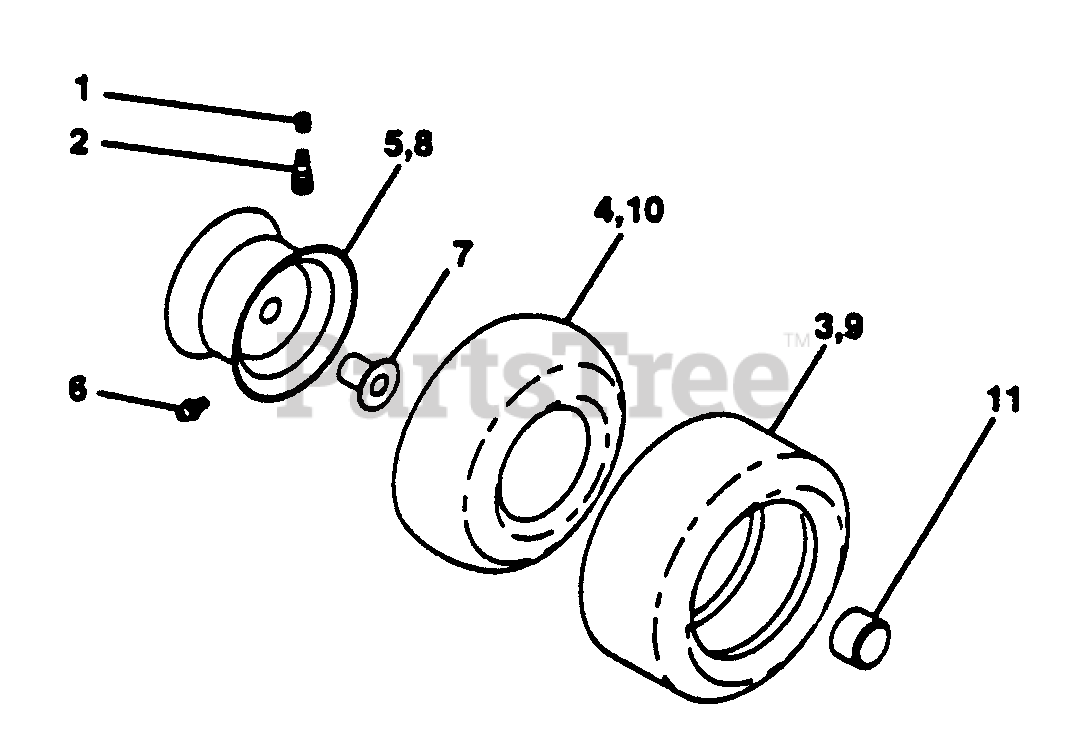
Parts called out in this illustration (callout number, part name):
1	Cap Valve Tire
2	Stem Valve
3	Tire F Ts 15 X 6 0 - 6 Service
4	Tube Front
5	Rim Asm 6" front White Service
6	Fitting Grease
7	Bearing Flange
8	Rim Asm 8" rear White Service
9	Tire R Ts 18x8 5-8 C Service
10	Tube Rear
11	Cap Axle Blk 1 50 X 1 00
